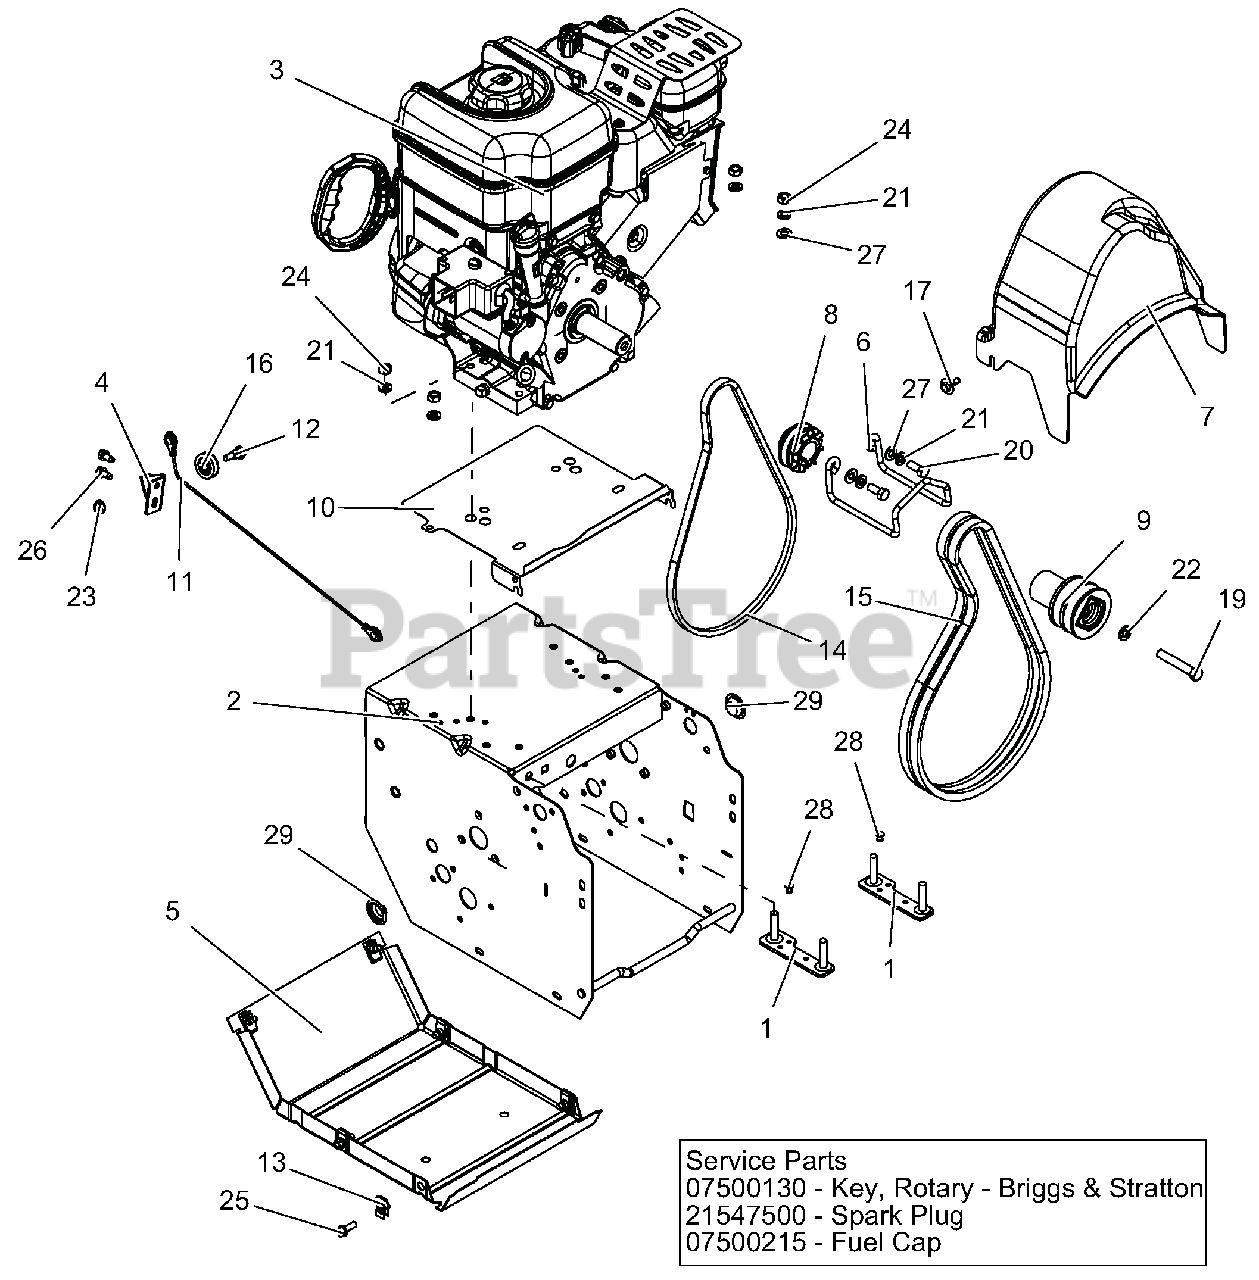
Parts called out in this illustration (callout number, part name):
1	STRAP, ENGINE BOLT-WELDMENT
2	FRAME, 920/921
3	ENGINE, BRIGGS SNOW 1150, 240V
4	BRACKET, CABLE PULLEY
5	COVER, BOTTOM
6	FINGER, BELT
7	BELT COVER
8	SHEAVE, DRIVE
9	SHEAVE,ATTACHMENT 2-GRV
10	BAFFLE,ENGINE,ARIENS SML BLOCK
11	CABLE, LOWER TRACTION (DELUXE)
12	BOLT, SHLDR-.375X.375X.25-20
13	NUT-RTNR .25-20X.56
14	V-BELT, 3L-WRAPPED
15	V-BELT, HA-RAW EDGE (SET)
16	PULLEY, CABLE
17	SCR-TAP .25-20X.5 CAPTIVE
19	BLT-HEX .38-24X2.25 YWZC GR5
20	BLT-HEX .31-24X.75 YWZC GR5
21	WSHR-LK .312X.097 HVY YWZC
22	@WSHR-LK .38X.094 REG YWZC
23	@NUT-LK-CTR-FLG .25-20 YWZC
24	@NUT-HEX .31-18 YWZC
25	BLT-HEX .25-20X.75 HWH YZ GR5
26	SCR-TAP .25-20X.50 HWH TR YWZ
27	@WSHR-FL-STL.344X.688X.065YWZC
28	RVT-POP .187 YZ
29	PLUG, HOLE - .875" NYLON
